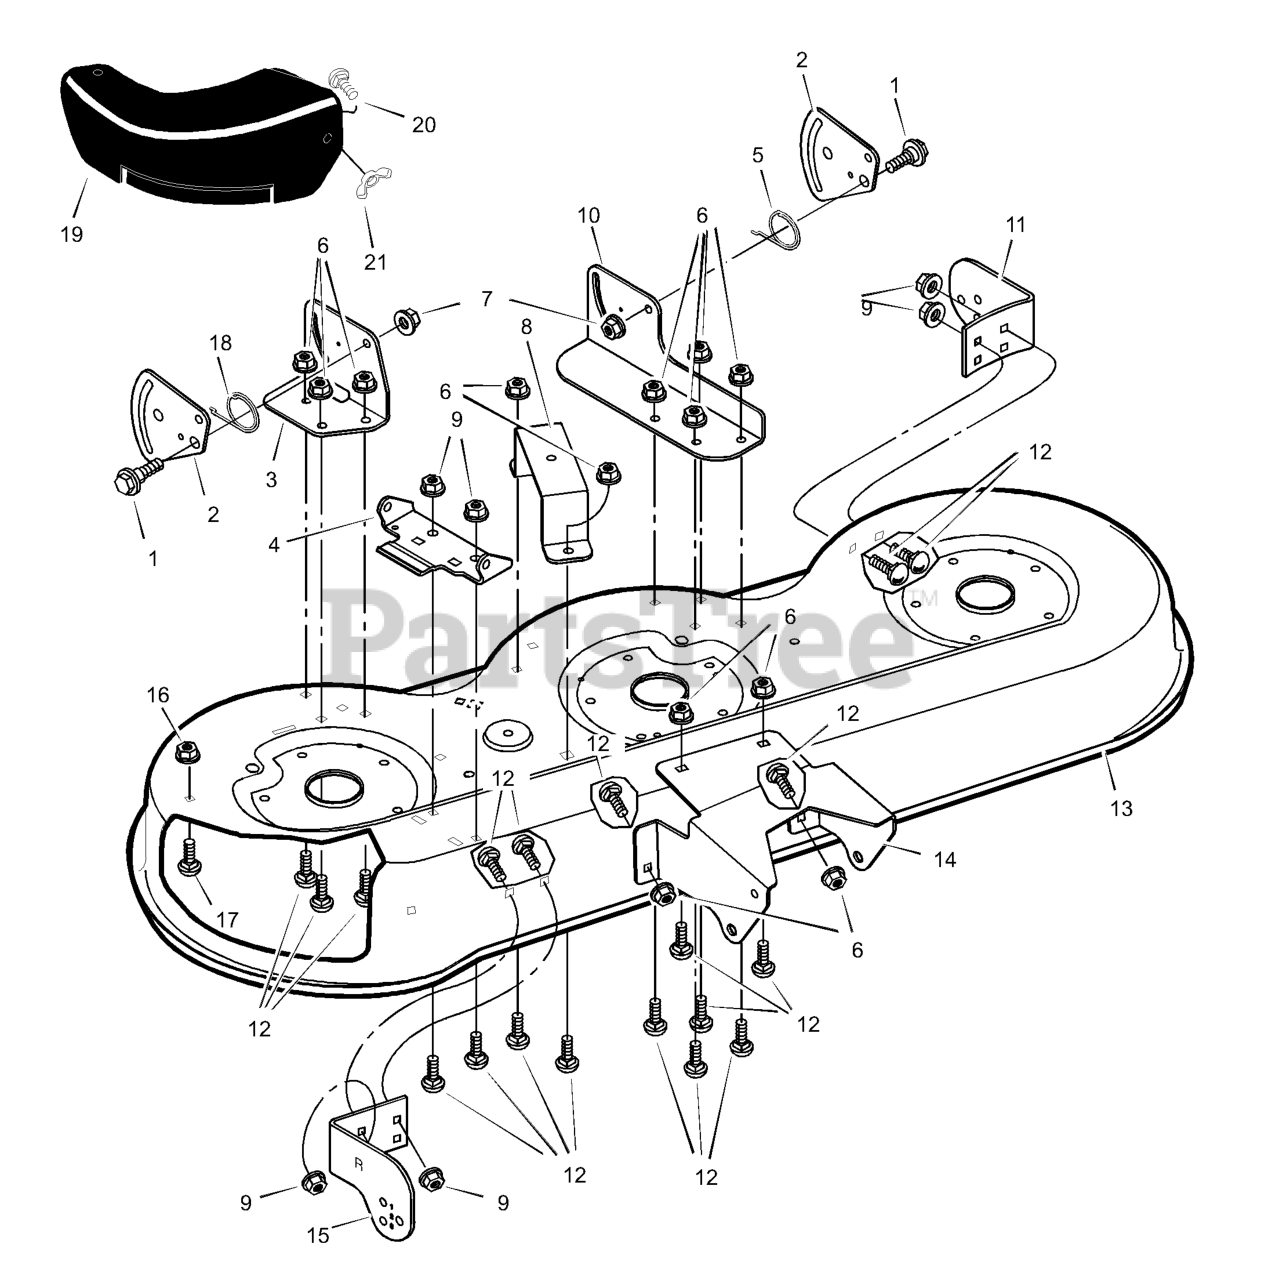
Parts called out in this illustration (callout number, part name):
1	Bolt, Shoulder
2	Plate, Suspension
3	Bracket, Right Rear
4	Bracket, Hinge
5	Spring, Left
6	Nut, Flange
7	Nut, Flange
8	Bracket, Bell Crank
9	Nut, Flange
10	Bracket, Left Lifter
11	Bracket, Left Gauge Wheel
12	Bolt, Carriage
13	Housing, Blade
14	Bracket, Front Deck
15	Bracket, Right Gauge Wheel
16	Retainer
17	Bolt, Carriage
18	Spring, Right
19	Cover, Mulcher
20	Bolt, Carriage
21	Wingnut
